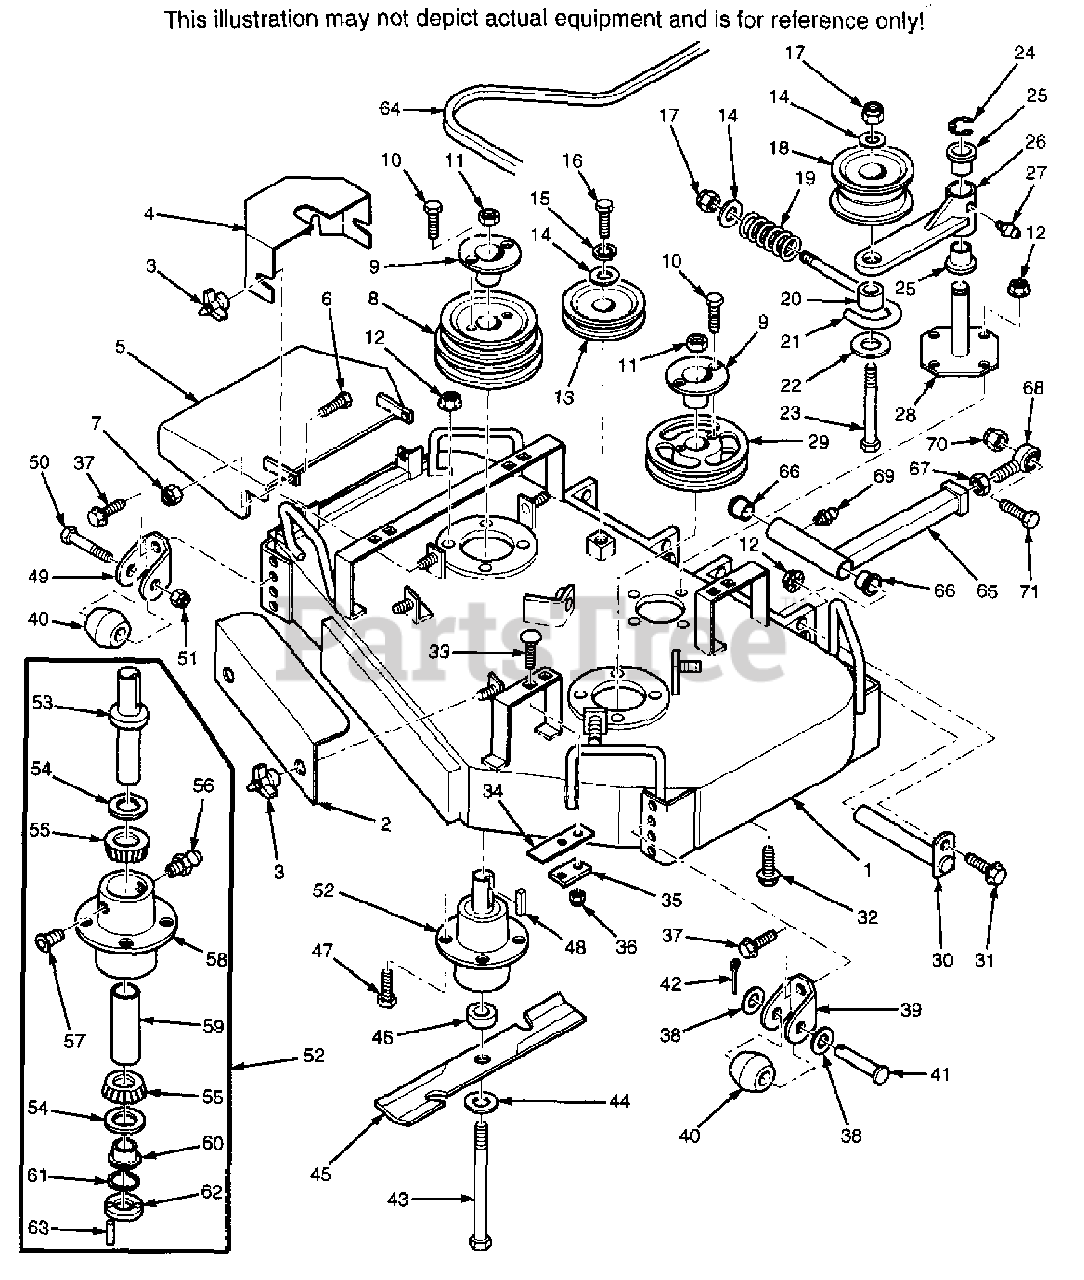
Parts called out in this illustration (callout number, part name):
1	CUTTER DECK
2	BELT COVER, FRONT
3	WING NUT 3/8-16
4	BELT COVER
5	DISCHARGE CHUTE
8	PULLEY, DOUBLE GROOVE
9	TAPERED HUB, 1" BORE
12	NUT, SERR. FLANGE 5/16-18
13	PULLEY, IDLER
14	FLAT WASHER, 3/8-.391 X .938 X .105"
15	LOCKWASHER, 3/8"
18	PULLEY, IDLER
19	SPRING, CUTTER DECK
20	SPACER
21	J-ROD
22	FLAT WASHER, 3/8-.375 X 1.500 X .060
24	RETAINING RING, 1 1/8 EXT. BASIC
25	BUSHING, SUPER OILUBE-1 1/8 ID.
26	IDLER ARM(INCLUDES ITEMS 25 AND 27)
27	GREASE FITTING, SELF TAP 1/4-28
28	IDLER PIVOT SUPPORT
29	PULLEY, LH SPINDLE
30	PUSH ROD SHAFT
31	SERR. FLANGE HH CPSCR, 5/16-18 X 1"
32	SERR FLANGE HH CPSCR, 5/16-18 X .75"
34	RUBBER PAD, DECK BUMPER
35	BACKUP PLATE, DECK PAD
36	NUT, ELASTIC STOP 1/4-20
37	SERR. FLANGE HH CPSCR, 3/8-16 X 1"
38	FLAT WASHER, 5/8-.656 X 1.312 X .095"
39	BRACKET, ANTI-SCALP WHEEL - LH FRONT
40	WHEEL, ANTI-SCALP
41	PIN, CLEVIS 5/8 X 4.0"
42	PIN, COTTER 5/32 X 1.50"
43	BOLT, HEX HEAD 5/8-11 X 9.50"
44	FLAT WASHER, 5/8-.688 X 1.750 X .134"
45	CUTTER BLADE, 21" STANDARD
45	CUTTER BLADE, 21" HI-LIFT
46	SPACER, SPINDLE BOTTOM
48	KEY, 1/4 X 1/4 X 2"
49	BRACKET, ANTI-SCALP WHEEL
50	BOLT, HEX HEAD 5/8-11 X 4.50"
51	NUT, ELASTIC STOP 5/8-11
52	SPINDLE ASSEMBLY, TAPERED BEARING
53	SPINDLE SHAFT, TAPERED BEARING
54	SEAL
55	TAPERED BEARING W/RACE
56	GREASE FITTING, STR. 5/16 SERR.
57	RELIEF FITTING, CUTTER SPINDLE
58	SPINDLE HOUSING, TAPERED BEARING
59	SLEEVE, CUTTER SPINDLE
60	SPINDLE BUSHING
61	RETAINING RING, 1" EXT. INVERTED
62	SPACER, CUTTER BLADE
63	ROLL PIN, 1/8 X 1/2"
64	BELT, CUTTER DECK DRIVE
65	PUSH ROD ASSEMBLY(INCLUDES 66 THRU 69)
66	BUSHING
67	NUT, 5/8-18 UNF
68	ROD END
69	GREASE FITTING - SELF THRD.
70	HEX NUT, 5/16-11 ELASTIC STOP
